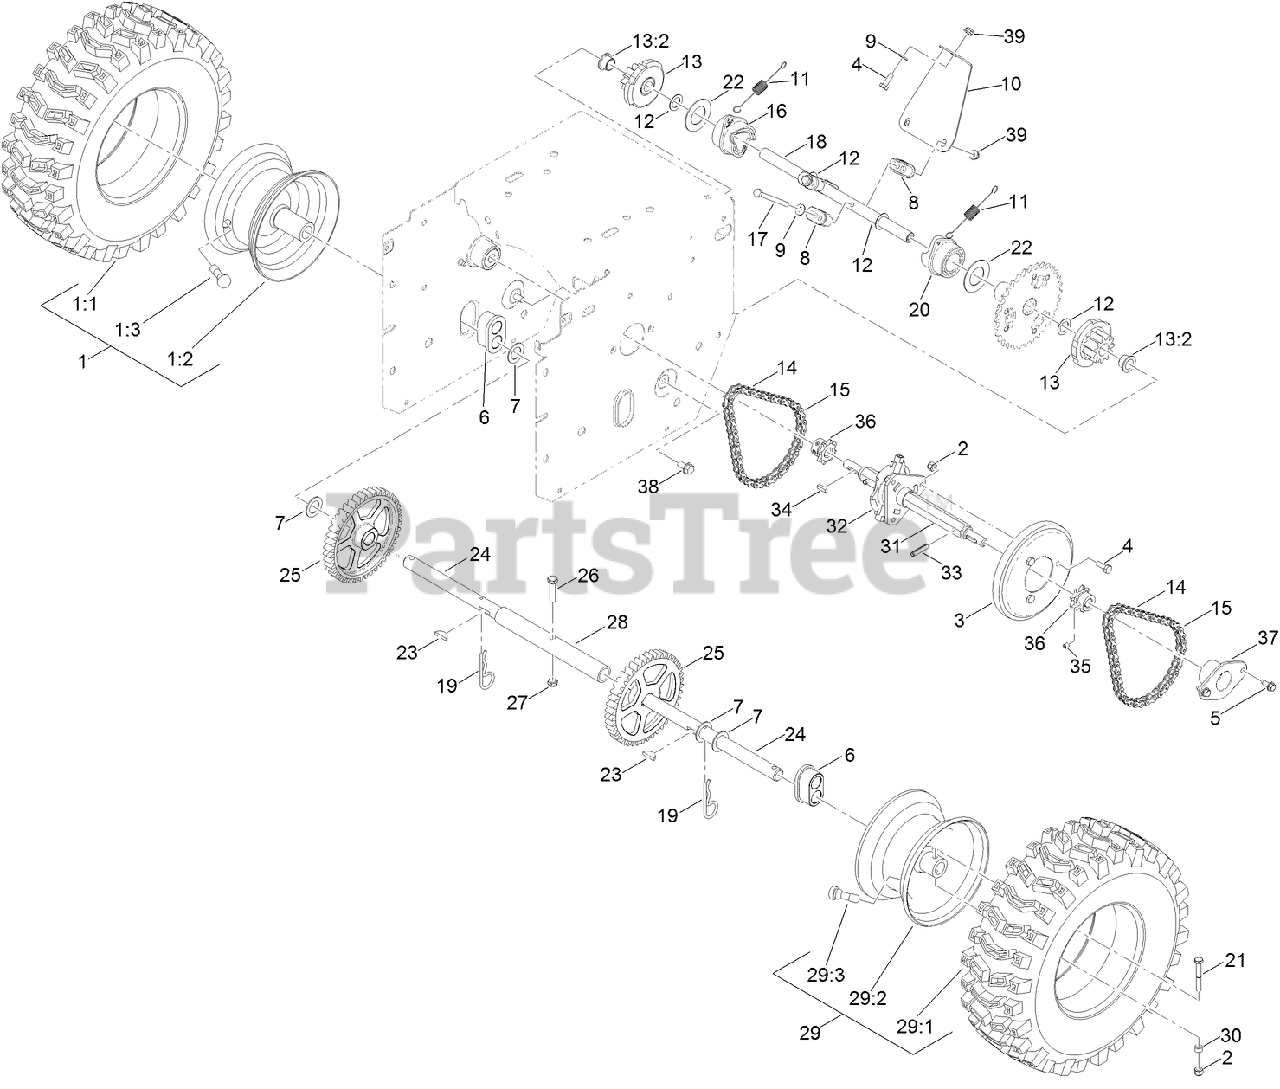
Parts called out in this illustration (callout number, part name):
1	RH WHEEL AND TIRE ASM
1:2	RIM W/VALVE STEM, GRAY
1:3	STEM-VALVE
2	NUT-LOCK, NI
3	WHEEL-FRICTION
4	SCREW-HH
5	SCREW-HWH
6	BEARING-AXLE
7	WASHER-THRUST
8	GUIDE-COLLAR
9	WASHER-FLAT
10	BRACE-COLLAR, SHIFT
11	SPRING-EXTENSION
12	WASHER-FLAT
13	11T GEAR ASM
13:2	BUSHING-FLANGE
14	CHAIN-ROLLER
15	LINK-CONNECTING
16	COLLAR-SHIFT, RH
17	SCREW-HH
18	SHAFT-INTERMEDIATE
19	PIN-HAIR
20	COLLAR-SHIFT, LH
21	SCREW-HH
22	WASHER-THRUST
23	KEY-WOODRUFF
24	SHAFT-AXLE
25	GEAR-AXLE, 44 TOOTH
26	SCREW-HH
27	NUT-LOCK, NI
28	TUBE-AXLE
29	LH WHEEL AND TIRE ASM
29:2	RIM W/VALVE STEM, GRAY
29:3	STEM-VALVE
30	SPACER-BLADE, ROTOR
31	SHAFT-HEX
32	TRUNNION-HEX
33	PIN-ROLL, SLOTTED
34	KEY-SQUARE
35	SCREW-HSH
36	SPROCKET-8 TOOTH
37	RETAINER-BEARING
38	SCREW-HWHTF
39	NUT-HF
